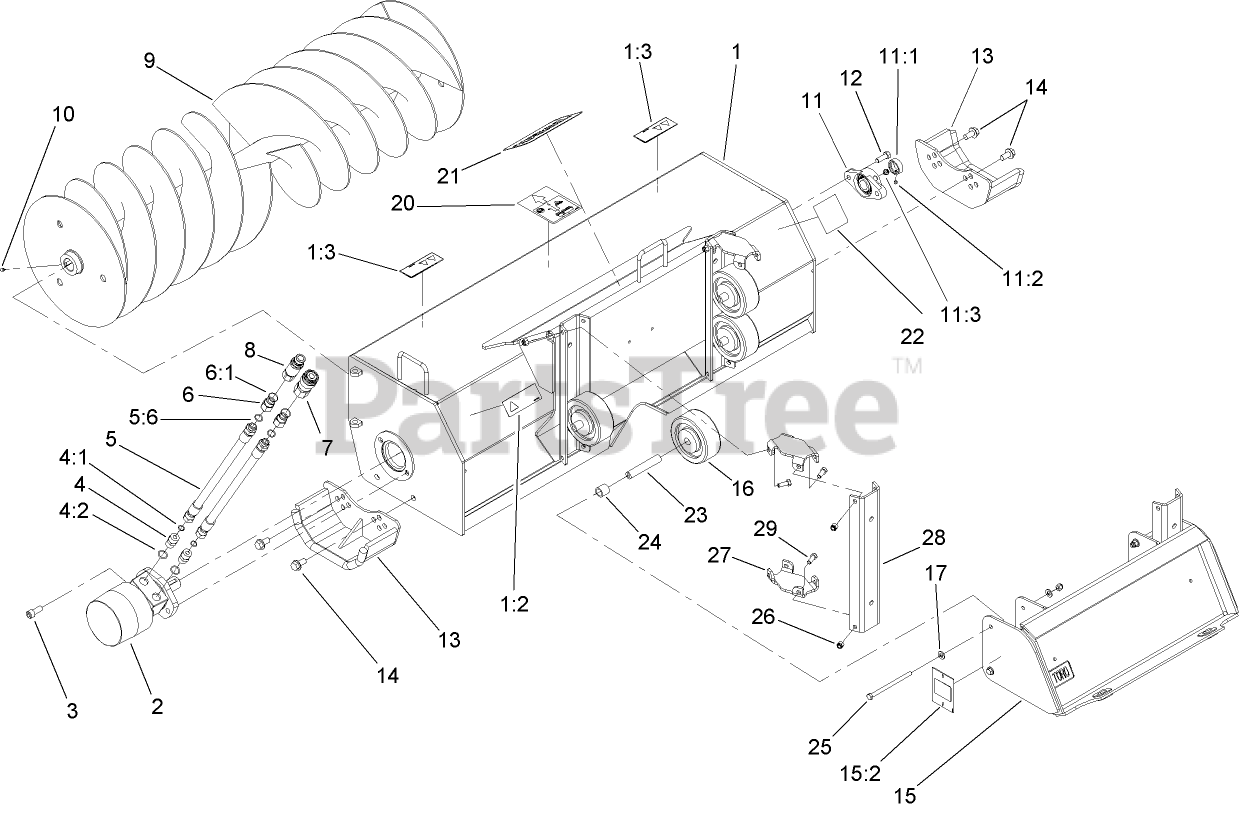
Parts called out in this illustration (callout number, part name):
1	FRAME ASM
1:2	DECAL-WARNING
1:3	DECAL-DANGER
2	HYDRAULIC MOTOR ASM
3	SCREW-HSH
4	FITTING-STRAIGHT
4:1	O-RING
4:2	O-RING
5	HOSE ASM
5:6	O-RING
6	ADAPTER-HYD
6:1	O-RING
7	COUPLER-FACE, FLUSH
8	NIPPLE-CONNECT, PRESSURE
9	FILLER SHAFT ASM
10	SCREW-HSH
11	BEARING
11:1	COLLAR W/SET SCREWS
11:2	SCREW-SET, HSH
11:3	FITTING-GREASE
12	SCREW-HH
13	SKID PLATE ASM
14	SCREW-HHF
15	QTACH ASM
15:2	DECAL-WARNING
16	ROLLER-FLOAT
17	WASHER-FLAT
20	DECAL-CENTER TRENCH
21	DECAL
22	DECAL
23	SPACER-FLOAT
24	SPACER-WHEEL
25	SCREW-HH
26	NUT-LOCK, NI
27	BRACKET-CAP, FLOAT
28	BRACKET-GUIDE, FLOAT
29	SCREW-HH
